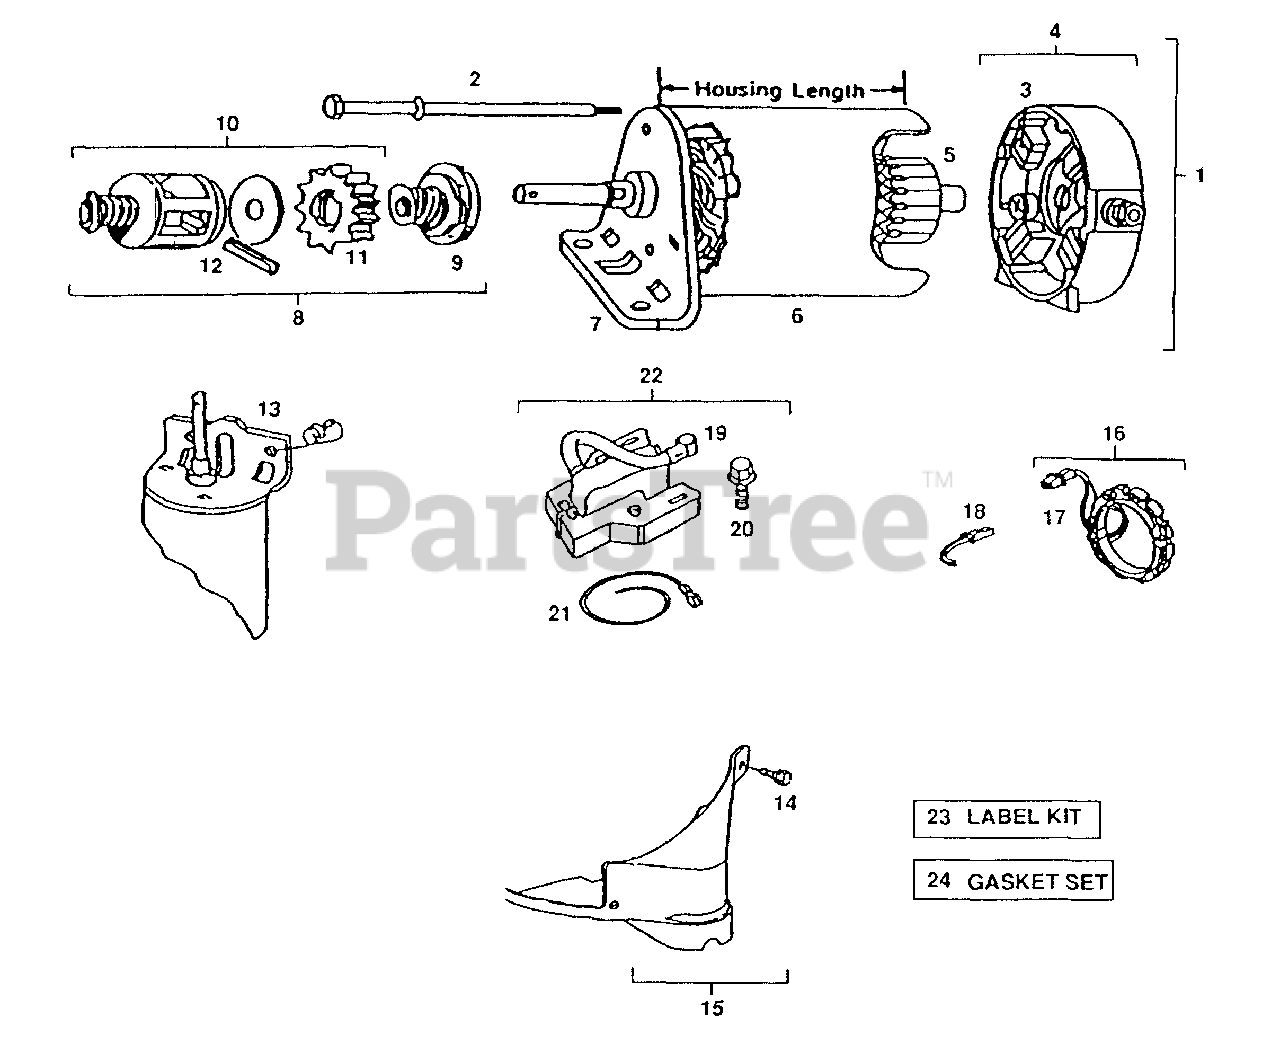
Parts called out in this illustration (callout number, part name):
1	Motor and Drive Assembly 12V, 4 3/8" Housing Length
2	Thru Bolt Assembly
3	Brush Assembly
4	End Cap Assembly Commutator
5	Armature Assembly
6	Housing Assembly
7	Drive End Cap Assembly
8	Drive Assembly
9	Clutch Assembly
10	Retainer and Pin
12	Roll Pin
13	Screw, Sem
14	Screw, Sem
15	Cover, Starter
16	Stator, Alternator (Dual Circuit)
17	Diode and Connector Assembly (Dual Circuit)
18	Alternator Harness Assembly (Dual Circuit)
19	Terminal, Ignition
20	Screw, Armature Mounting Sem
21	Wire, Ground
22	Armature, Magneto
23	Decal, Label Kit
24	Gasket Set
